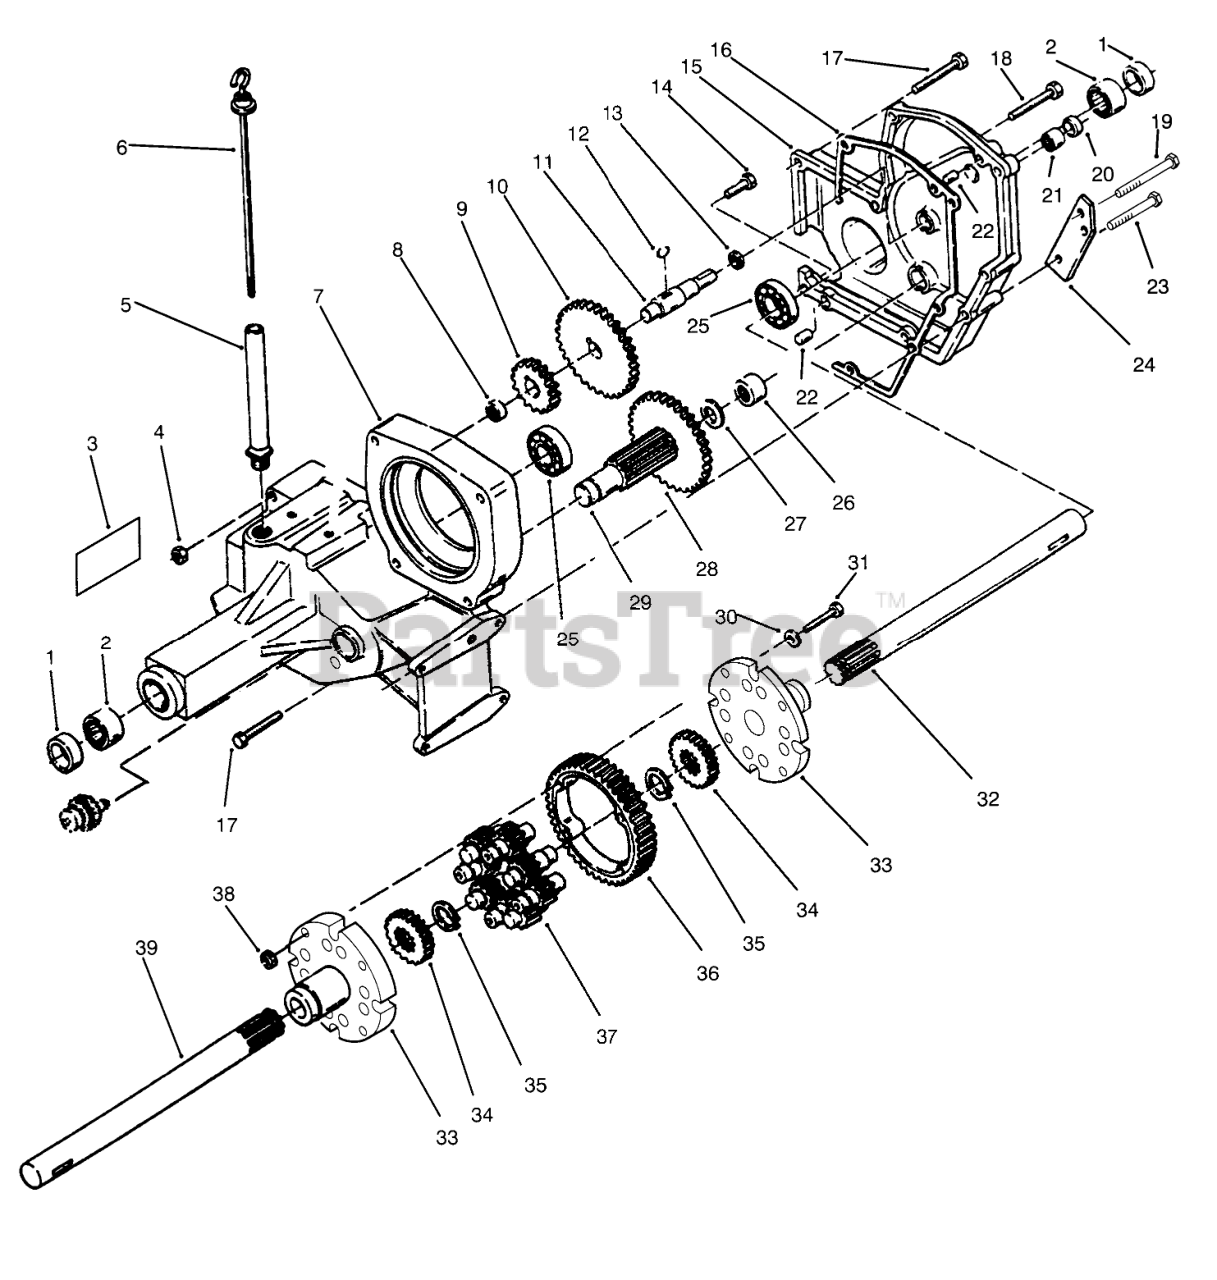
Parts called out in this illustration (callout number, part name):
1	SEAL-OIL
2	BEARING
3	DECAL - DANGER
4	NUT-LOCK, NI
5	NIPPLE-TRANS FILL
6	Dipstick
7	Case-Transaxle,RH (Incl. Ref. #3)
8	BEARING-NEEDLE
9	GEAR 20 TEETH
10	GEAR 46 TEETH
11	SHAFT GEAR
12	WOODRUFF KEY
13	Race Thrust
14	SCREW-HH
15	CASE TRANS LH
16	GASKET-TRANSMISSION
17	SCREW-HH
18	SCREW-HH
19	SCREW-HH
20	Seal
21	NEEDLE BEARING
22	PIN-LOCATING
23	SCREW-HH
24	BRACKET-BRAKEB
25	BEARING-BALL
26	BEARING-NEEDLE
27	WASHER-THRUST
28	GEAR 46T
29	PINION SHAFT
30	WASHER
31	BOLT-HEX
32	AXLE-REAR LH
33	END CAP-DIFFERENTIAL
34	GEAR-AXLE DIFFERENTIAL
35	RING-SNAP
36	GEAR-DIFFERENTIAL RING, 43T
37	GEAR-PINION, 11T
39	AXLE-REAR RH
